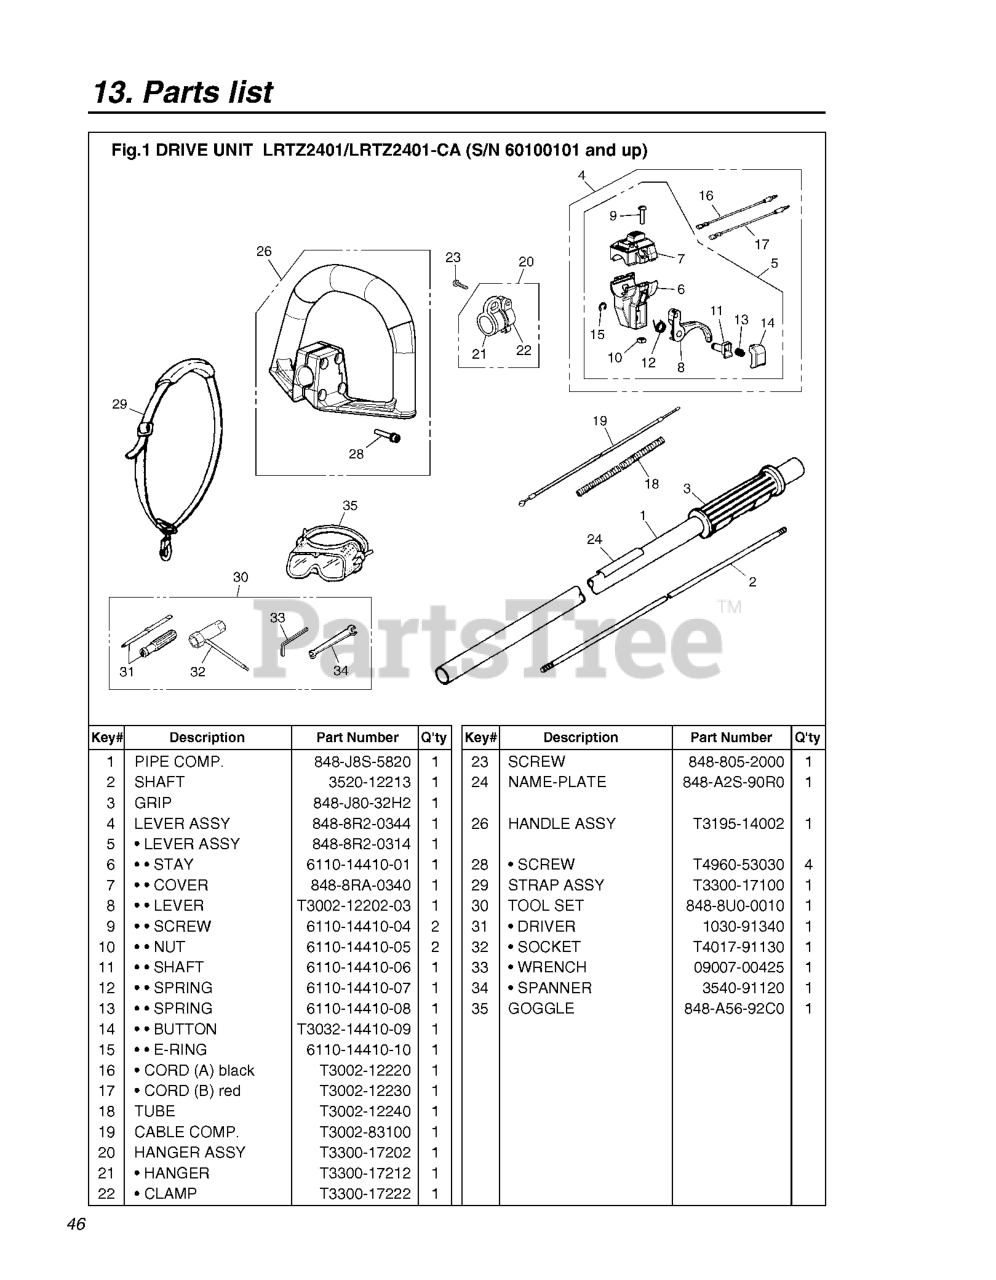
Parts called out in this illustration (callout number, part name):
1	PIPE COMP
4	LEVER COMP (RPLS 8488R20343)
5	LEVER (FLEX. LEVER)(RPLS -13)
7	COVER COMP (RPLS 611014410-02)
16	CORD (A), BLACK
17	CORD (B), RED
20	HANGER COMP.
21	HANGER
26	HANDLE ASSY. (RPLS T319514001)
29	HARNESS-ASSY***
30	TOOL-SET
35	GOGGLExxx (RPLS
